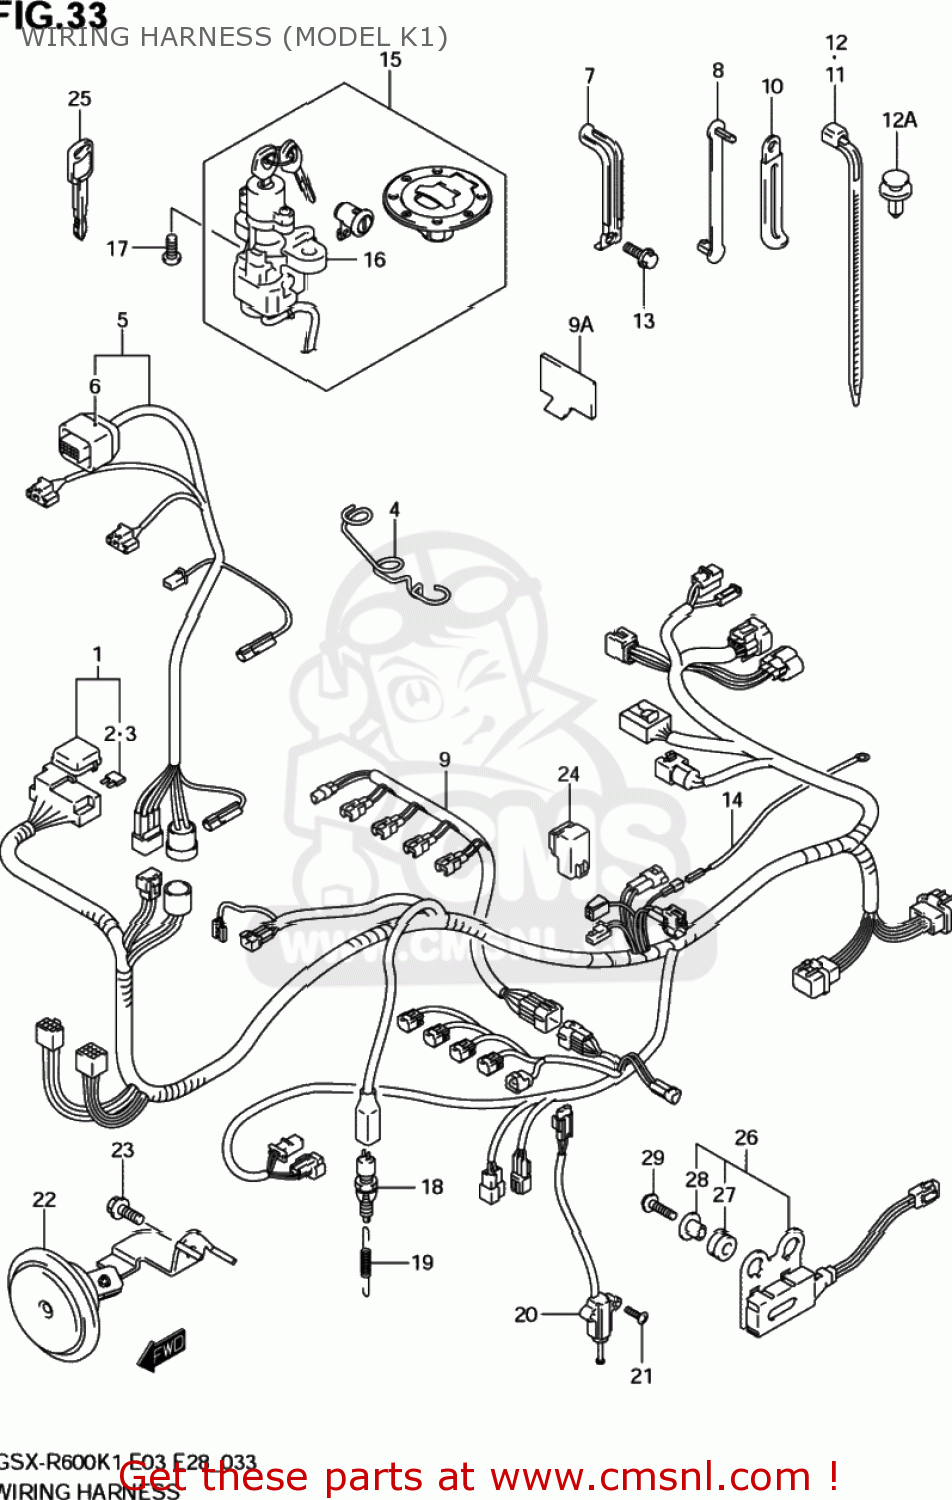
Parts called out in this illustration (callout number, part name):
1	HARNESS,WIRING NO.1
2	FUSE(10A)
3	FUSE(15A)
4	GUIDE,WIRING HARNESS
5	HARNESS,WIRING NO.2
6	COVER,SPEEDOMETER COUPLER
7	CLAMP,WIRING HARNESS
8	CLAMP(L:63)
9	WIRE,INJECTOR LEAD
9A	PROTECTOR,WIRING HARNESS
10	CLAMP(L:65)
11	CLAMP(L:125)
12	CLAMP
12A	CLIP
13	BOLT
14	WIRE,OIL PRESSURE SWITCH LEAD
15	LOCK SET
16	LOCK ASSY,STEERING
17	BOLT(8X20)
18	SWITCH ASSY,STOP LAMP
19	SPRING
20	SWITCH ASSY,SIDE STAND
21	BOLT
22	HORN ASSY
23	BOLT
24	RELAY ASSY
25	KEY,BLANK
26	RESISTOR ASSY
27	CUSHION
28	SPACER(6.5X10X11.6)
29	SCREW(6X25)
